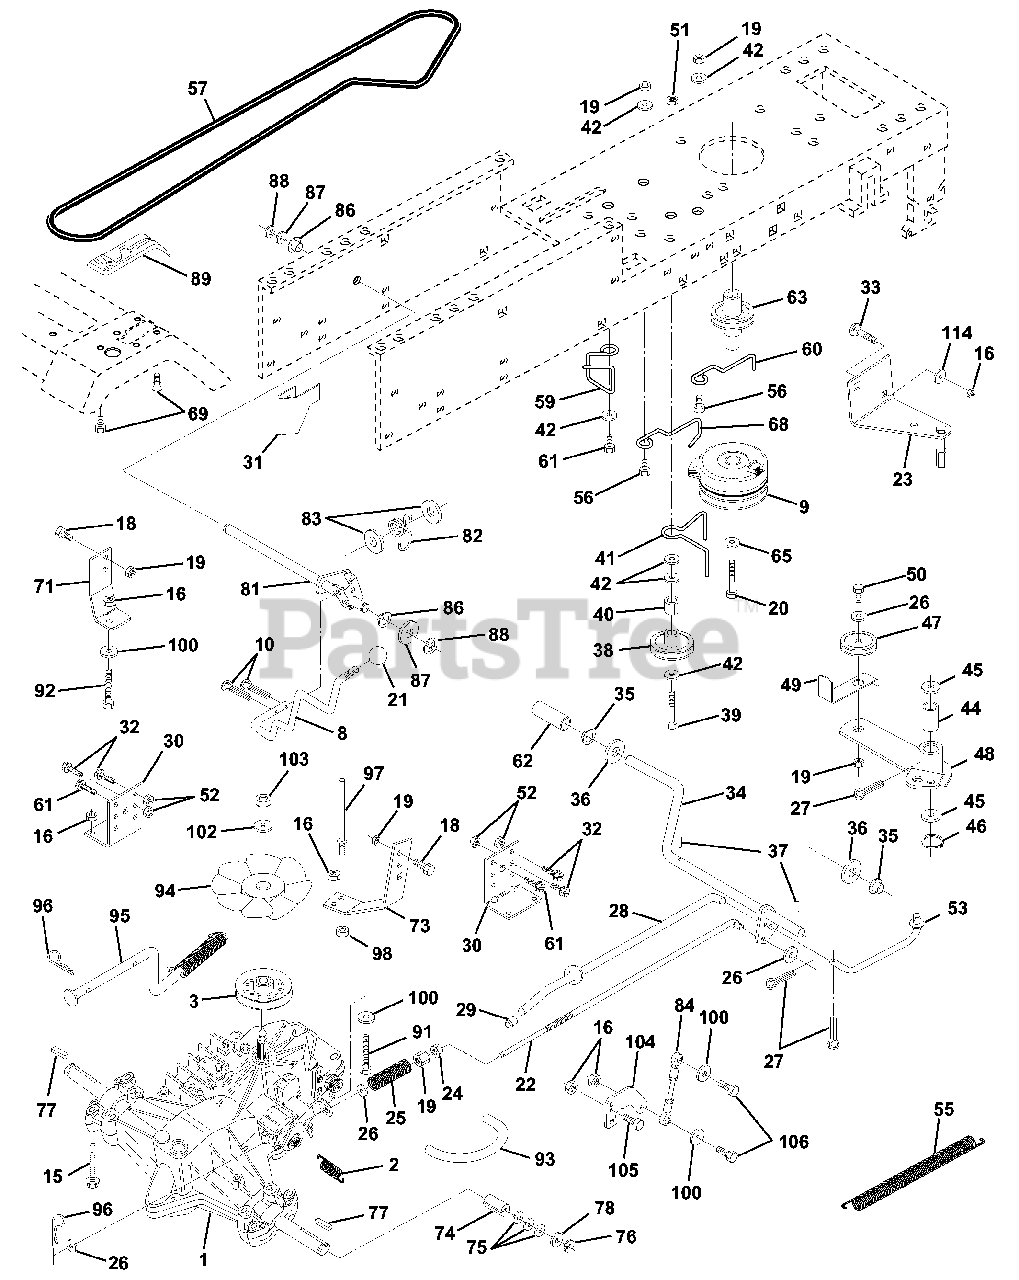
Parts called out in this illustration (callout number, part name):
1	Transaxle Assembly, 310-0650
2	Spring, Return, Brake
3	Pulley, Transaxle
8	Rod Shift Fender y T
9	Clutch, Elect. EVX LT Mag 5217-2
10	Pin Cotter 1/8 x 1 CAD
15	Bolt Hex Flghd 5/16-18 Gr. 5
16	Nut Lock Hex W/Ins. 5/16-18 Unc P
18	Bolt Fin Hex 3/8-16 Unc x 1 Gr. 5
19	Nut Lock Hex W/Wsh 3/8-16 Unc
20	Bolt Hex 7/16-20 x 4-1/4 Ga. 5
21	Knob, Deluxe
22	Rod, Brake Hydro
23	Bracket, Asm Clutch Mtg EVX
24	Nut
25	Spring, Brake Rod
26	Washer
27	Pin Cotter 1/8 x 3/4 CAD.
28	Rod, Parking Brake
29	Cap, Parking Brake
30	Bracket, Transaxle
31	Keeper Belt Lh
32	Bolt Hex Hd 5/16-18 Unc x 3/4
33	Bolt Rdhd Sqnk 5/16-18 UNC x 3/4
34	Shaft, Foot Pedal
35	Bearing, Nylon
37	Pin, Roll
38	Pulley, Idler, Flat
40	Spacer, Split
41	Keeper, Belt Retainer
42	Washer 13/32 x 13/16 x 12 Gauge
44	Bearing, Nylon
45	Washer, Hardened
46	Ring, Klip
47	Pulley, Idler, V-Groove
48	Bellcrank Assembly
49	Retainer, Belt
50	Bolt
52	Nut Crownlock 5/16-18
53	Link, Clutch
55	Spring, Return, Clutch
56	Bolt Fin Hex 3/8-16 UNC x 1-1/4
57	V-Belt, Ground Drive
59	Keeper, Center Span
60	Keeper Belt Engine
61	Screw Thdrol. 3/8-16 x 3/4 Ty. TT
62	Cover, Pedal
63	Pulley, Clutch Electric EVX
65	Washer
68	Keeper Belt Engine
71	Strap Torque Lh Hydro
73	Strap Torque Rh Hydro
74	Spacer, Split
75	Washer 25/32 x 1-1/4 x 16 Gauge
77	Key, Square
78	Washer 25/32 x 1-5/8 x 16 Gauge
81	Shaft Asm. Cross Hydro
82	Spring Torsion T/A
83	Washer 17/32 x 3/4 x 16 Ga.
84	Rod, Tie Hydro
86	Bushing Rod Steering 629/632 ID
87	Washer 21/32 x 1-1/4 x 16 Ga.
88	Ring Klip #5304-62
89	Console, Shift
91	Bolt Fin Hex 5/16-18 x 2-1/4
92	Bolt Fin Hex 5/6-18 Unc x 1-1/2
93	Line Fuel Hydro 4"
94	Fan, Hydro 7"
95	Control Asm Bypass Hydro
96	Retainer Spring 1" Zinc/Cad
97	Keeper Belt Rh Hydro
98	Nut Keps Hex 3/8-16 Unc
100	Washer 11/32 x 3/4 x 16 Ga.
102	Washer, Bellville .50 ID x 1.50 D
103	Nut Nylon Insert 1/2-20 Unf.
104	Arm, Control Hydro
105	Screw Cap Hex 5/16 x 18 x 1
106	Bolt Fin Hex 5/16-18 Unc x 1-1/4
114	Washer 11/32 x 3/4 x 14 Ga.
